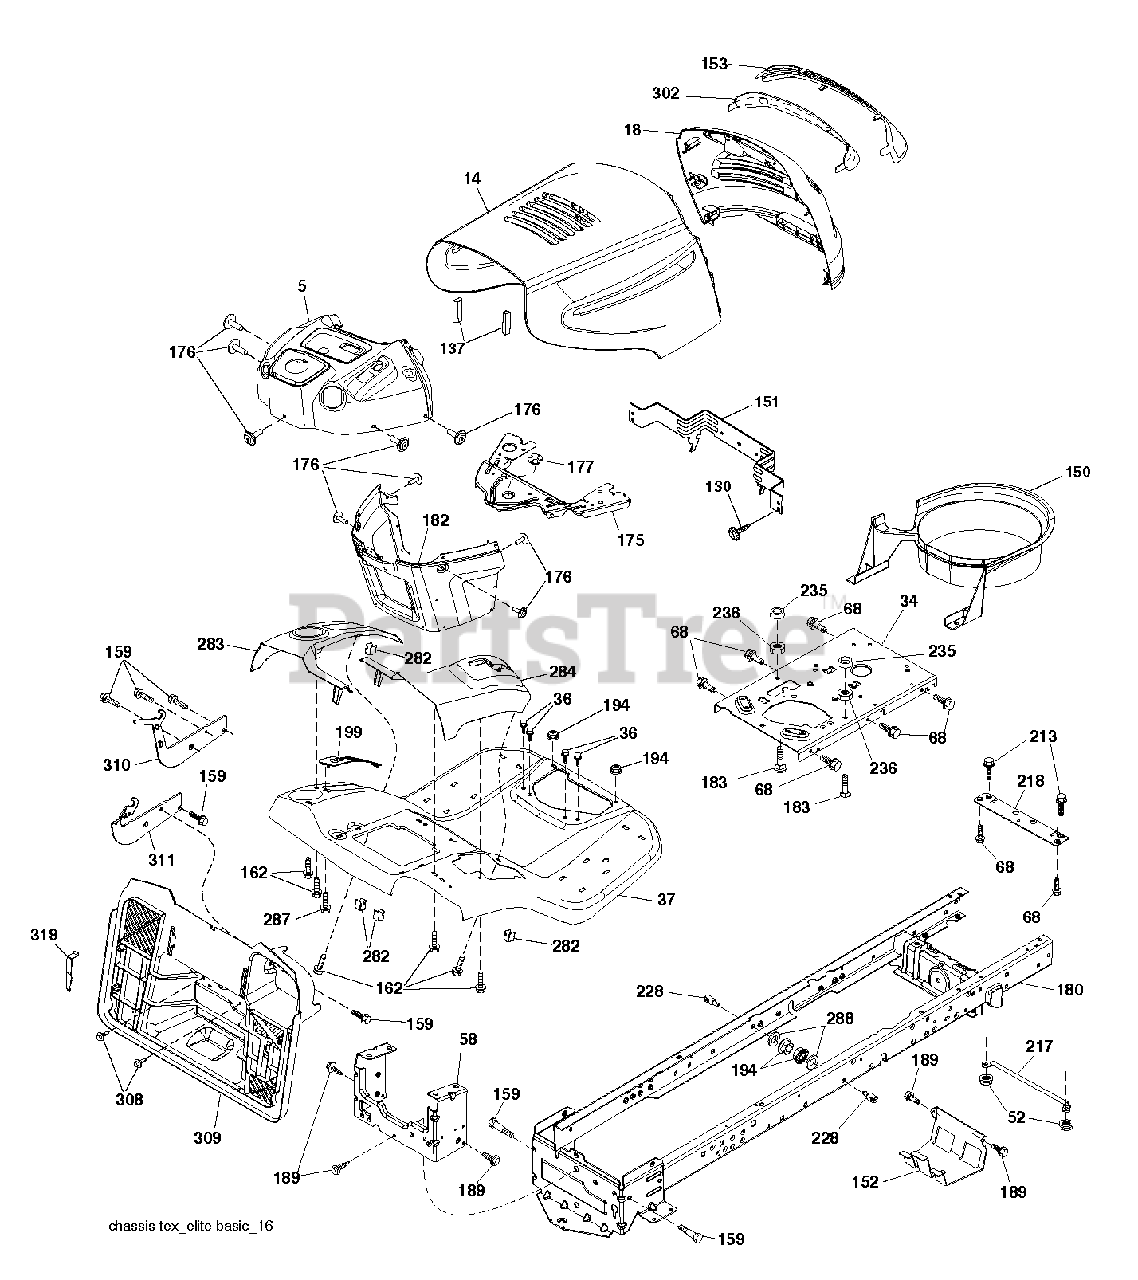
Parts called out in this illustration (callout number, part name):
5	DASH.P/L.TEX.CBL.CL.N/CHK.BLAC
14	HOOD.PNT.STL.ELITE.TOPLVRS.667
34	PLATE.ENGINE.WELDED.CHASSIS
36	SCREW 5/16"
37	FENDER.TEX.SRD.CRD.BASE
52	LOCKNUT
58	DRAWBAR UPPER 2PC SMALL FENDER
130	SCREW.#10 X 0.750.BOS THREAD
137	BUMPER.HOOD.LARGE.1.75"
150	DUCT.INTAKE.AIR.KAW
151	BRACKET PIVOT
152	SHIELD BROWNING
153	LENS.GRILLE.BASIC.BAR.LT.CLR
159	SCREW, 3/8-16X3/4
162	SCREW.HI-LO.CONSOLE
175	CROSSMEMBER.LT
176	SCREW.#10-24X5/8.RN.QU
177	BUSHING STEERING
180	CHASSIS.WLDMNT.14GA.2PC.18".TI
182	DASH.LOWER.LT.CCS
183	BOLT.5/16-18X1-1/4 FULL THD
189	SCREW
194	NUT LOCK HEX FLANGE 5/16-18
213	BOLT
217	ROD.PIVOT.HOOD
218	X-PIECE.HOOD.STOP.NON/
228	STUD.FASTNER.W/ANTI-ROTATE
235	SPACER FENDER
236	NUT.CENTERLOCK.5/16-
282	CLIP.RETAINER.CONSOLE.LT.HUSQ
283	CONSOLE.DECKLIFT.LH.SRD.TEXCRD
288	WASHER
302	INSERT LENS REFLECTIVE
308	BOLT, 5/16-18 X 1 3/4
309	BACKPLATE.BAGGER.V2.SRD
310	LH.ADJUST.HANGER.BRACKET.ASM
311	RH.ADJUST.HANGER.BRACKET.ASM
319	BRACKET.ACTUATOR.BAGGER.SRD
